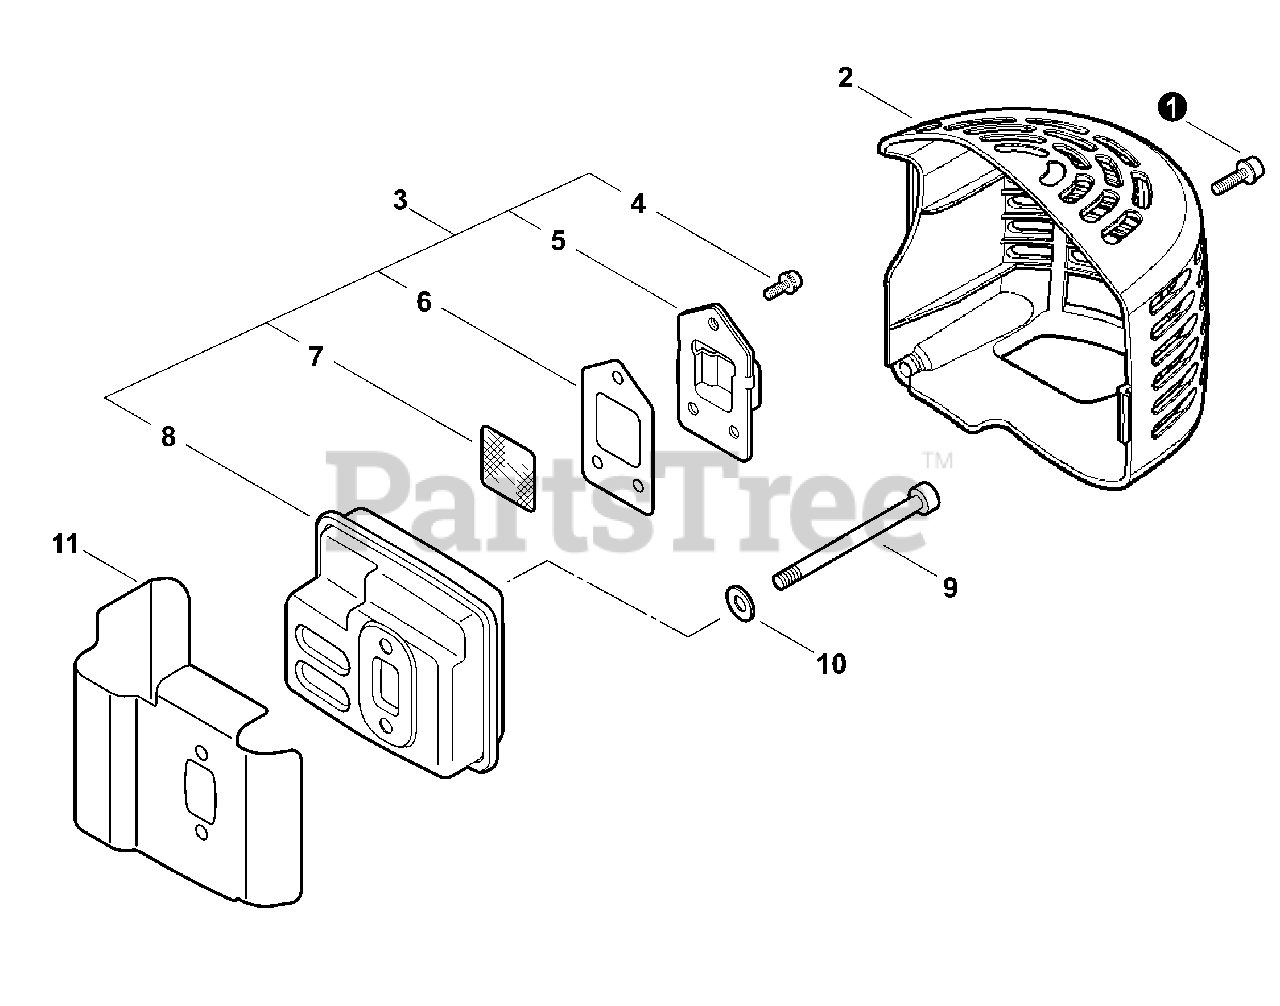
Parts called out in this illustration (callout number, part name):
1	SCREW - 5×16
2	COVER, EXHAUST
3	SCREW - 4×10
4	GUIDE, EXHAUST
5	GASKET, EXHAUST
6	SCREEN, SPARK ARRESTOR
7	SCREW - 5×55
8	WASHER - 5
10	ARANDELA - 5
